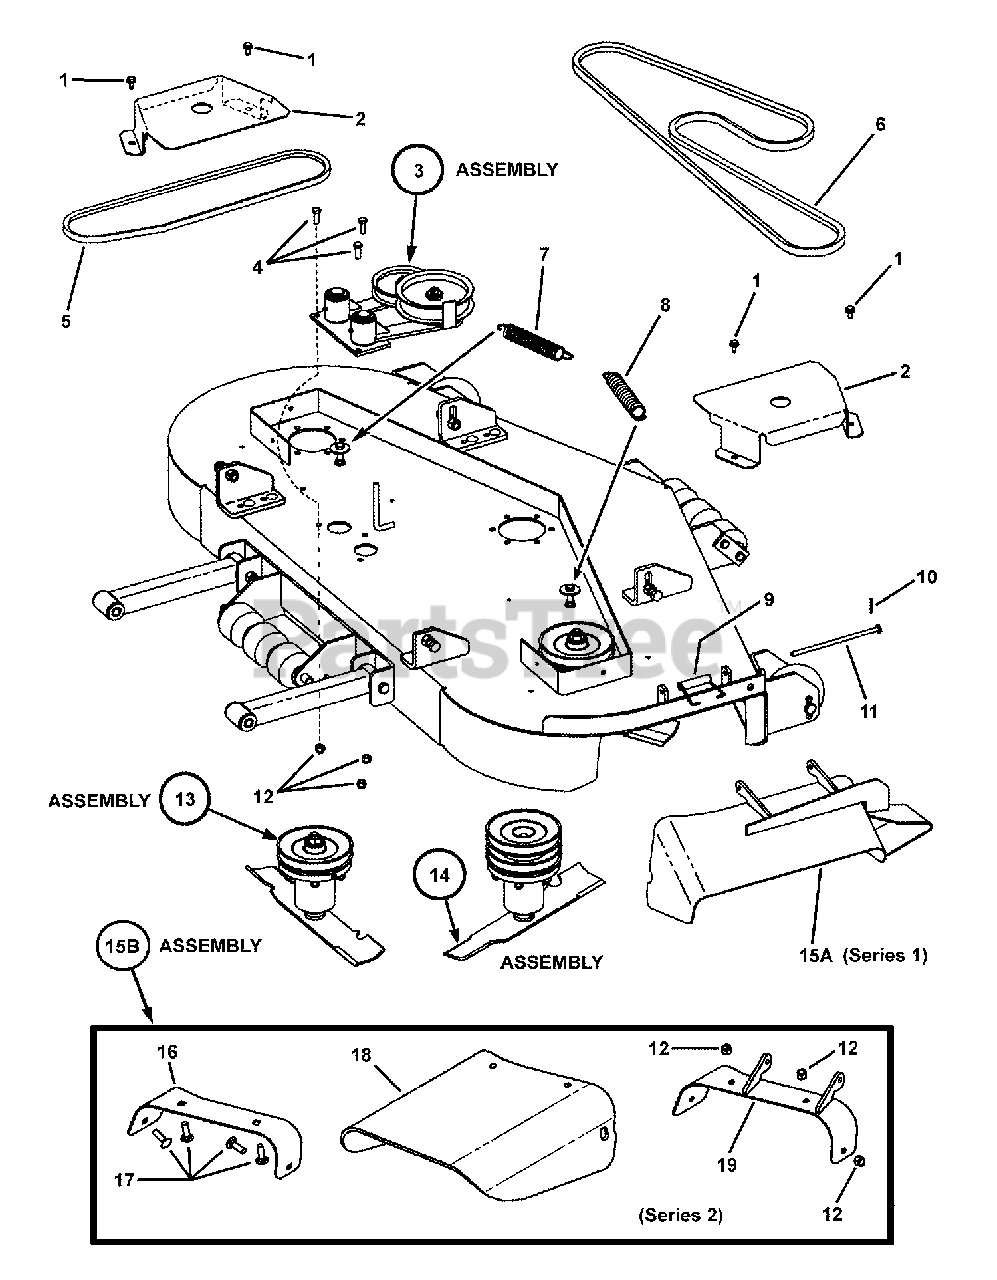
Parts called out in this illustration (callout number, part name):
1	SCREW, 5/16-18 x 5/8" Hex Washer Self-Tap
2	BELT COVER
3	ASSEMBLY, Idler (see breakdown on Idler Assy page)
4	BOLT, 3/8-16 X 1" GD5 CZ
5	*BELT, Primary (HB Section, 94.20" effective length)
5	*BELT, Primary (HB Section, 94.2" effective length)
6	*V-BELT, Secondary- 61" (HB Section, 127.0" effective length)
7	SPRING, Idler (1.17" O.D. x 7.5" long)
8	SPRING, Idler Primary (.90" O.D. x 10" long)
8	SPRING, Idler Primary (1.25" O.D. x 10" long)
9	SPRING, Chute
10	PIN, 3/32 x 1" Cotter
11	PIN, Chute Hinge
12	NUT, 3/8-16 HEX NYLON LOCK
13	ASSEMBLY, Spindle (see breakdown on Deck Spindle Assy page)
14	ASSEMBLY, Center Spindle (see breakdown on Deck Spindle Assy page)
15A	WELDMENT, 61" Chute Deflector (Series 1)
16	DEFLECTOR BOTTOM (61" Deck)
17	BOLT, 3/8-16 x 1-1/4" Square Neck Carriage, GR 5
18	CHUTE, Rubber (61" Deck)
19	WELDMENT, 61" Discharge Chute
